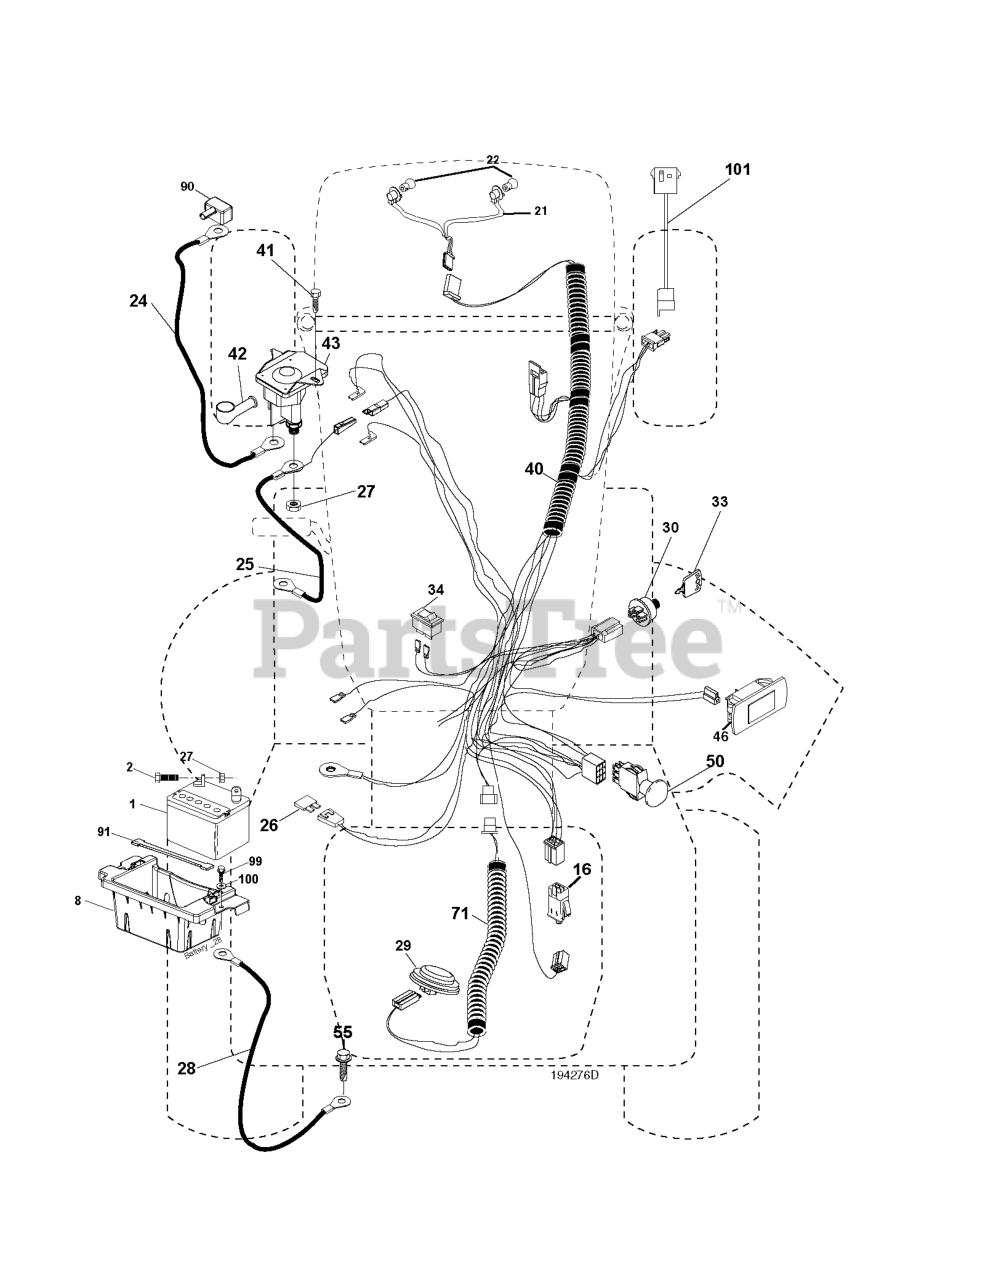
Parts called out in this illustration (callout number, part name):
1	BATTERY 12V .35 AMP
2	BOLT.HEX.1/4.X.3/4.DICHROMATE
8	BOX.BATTERY.MOUNT.FRONT.LT
16	SWITCH INTERLOOK PUSH-IN
21	HARNESS ASSY LIGHT
24	CABLE.BATT.POS.WIRE.TG.DA SOL
25	CABLE.START.RED.17.5".
26	FUSE 20AMP
27	NUT
28	CABLE GROUND 6 GA 21" 90T BLK
29	SWITCH.SEAT.DELTA.OPC.
30	SWITCH.IGN.DELTA.W.LGH.ROS
33	KEY MLD GEN DELTA
40	HARNESS.IGN.DASH.HUQ/P
41	SCREW
42	TERMINAL COVER
43	SOLENOID.W/BRASS.PLUNGER
46	RP.GUAGE.SRVCMNDR.HRMTR.
50	RP.PTO.SWITCH.8 TERMINAL.BLACK
55	SCREW 5/16"
71	HARNESS-CHASSIS SUB
90	COVER.TERMINAL.BATTERY
91	STRAP.BATTERY.MOUNT.FRONT(2 2)
99	SCREW HEXWSHR 1/4-20X3/4
100	WASHER
101	PIGTAIL.MATNLK.NEW.HAR
